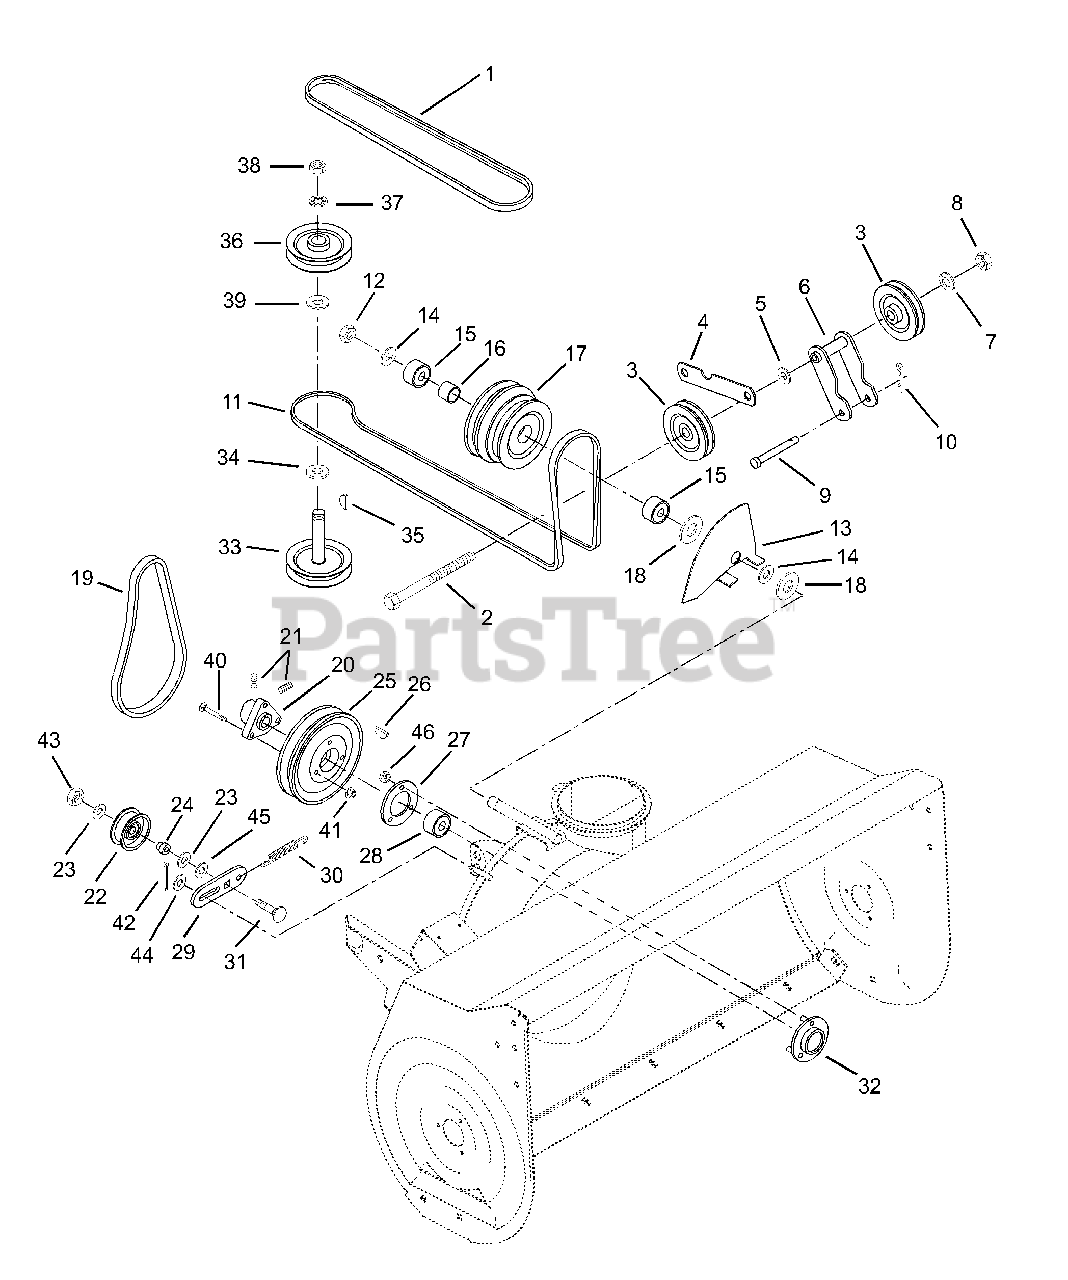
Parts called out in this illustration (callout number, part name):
1	V-Belt (Main Drive)
2	Bolt-Hex .38-16 x 5.00 Grade 2
3	Idler-V 3.00 x .38
4	Strap
5	Washer-Flat-Steel .754 x 1.000 x .032
6	Idler Bracket
7	Washer-Lock .375 x .115
8	Nut-Hex .375-16 Grade 2
9	Clevis Pin 3/8 x 3
10	Pin-Hair Internal .08 x .38 x 1.42
11	V-Belt 120.25 x .53 - Mule Drive
12	Nut-Locking-Center .75-10
13	Shield
14	Washer-Flat-Steel .781 x 1.250 x .059
15	Bearing-Ball .750 x 1.781 x .61
16	Spacer 1.00 x .770/.760 x .813
18	Washer-Flat-Steel .781 x 1.500 x .188
19	V-Belt 36-13/16 x 17/32
21	Screw-Set .31-18 x .38
22	Idler
23	Washer-Flat-Steel .390 x .88 x .18
24	Spacer, Flanged .390 x .500 x .781
25	Pulley-V 9.0 x 1.25
26	Key-Woodruff .188 x .875 x .38
27	Flange-Spherical
28	Bearing-Ball 1.0 x 2.0 x .56
29	Idler Arm
30	Spring-Tension .090 x .75 x 3.50
31	Bolt-Round Head Square Neck .38-16 x 1.75 Grade 5
32	Bearing Flange
33	Spindle Shaft
34	Spacer .755 x 1.250 x .370
35	Key-Woodruff .188 x .75
36	Pulley-V 4.50 x .75
37	Washer-Lock Internal .750 x .050
38	Nut-Jam .75-10
39	Washer-Locking .75 x .188
40	Bolt-Serrated Round Head Slotted .31-18 x .87
41	Nut-Flange .312-18
42	Pin-Cotter .12 x .75
43	Nut-Locking-Center .38-16
44	Washer-Flat-Steel .382 x .812 x .023
45	Washer-Flat-Steel .438 x 1.00 x .083
46	Washer-Flat-Steel .38 x .875 x .083
